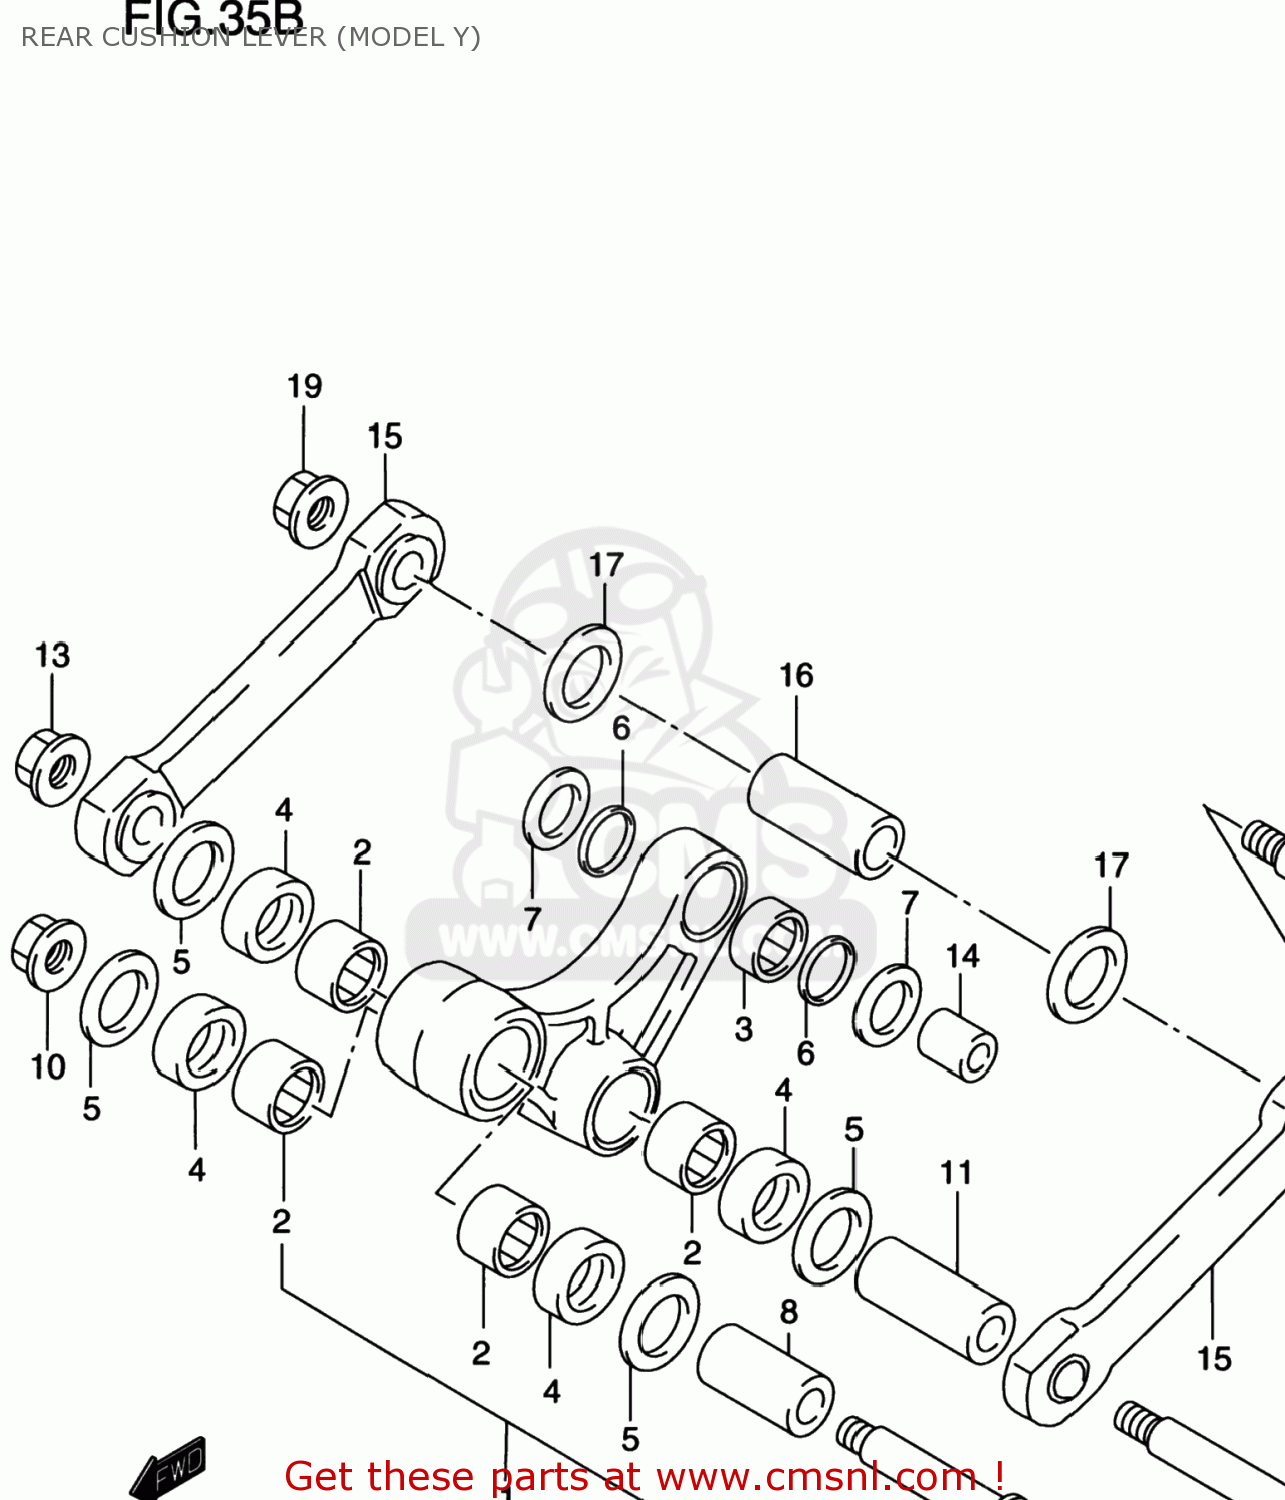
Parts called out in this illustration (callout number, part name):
1	LEVER SET,RR CUSHION
2	BEARING(20X27X15)
3	BEARING(16X22X12)
4	SEAL,CUSHION LEVER DUST
5	WASHER,THRUST SWINGARM RR
6	SEAL,OIL(16X22X2.5)
7	WASHER,THRUST LVR CUSHION RR
8	SPACER,CUSHION LEVER FR
9	BOLT,RR CUSHION LEVER FR
10	NUT 12MM
11	SPACER,RR CUSHION
12	BOLT,RR CUSHION
13	NUT 12MM
14	SPACER,RR CUSHION LEVER RR
15	ROD SET,RR CUSHION
16	SPACER,RR CUSHION
17	WASHER,THRUST SWINGARM RR
18	BOLT,RR CUSHION
19	NUT 12MM
